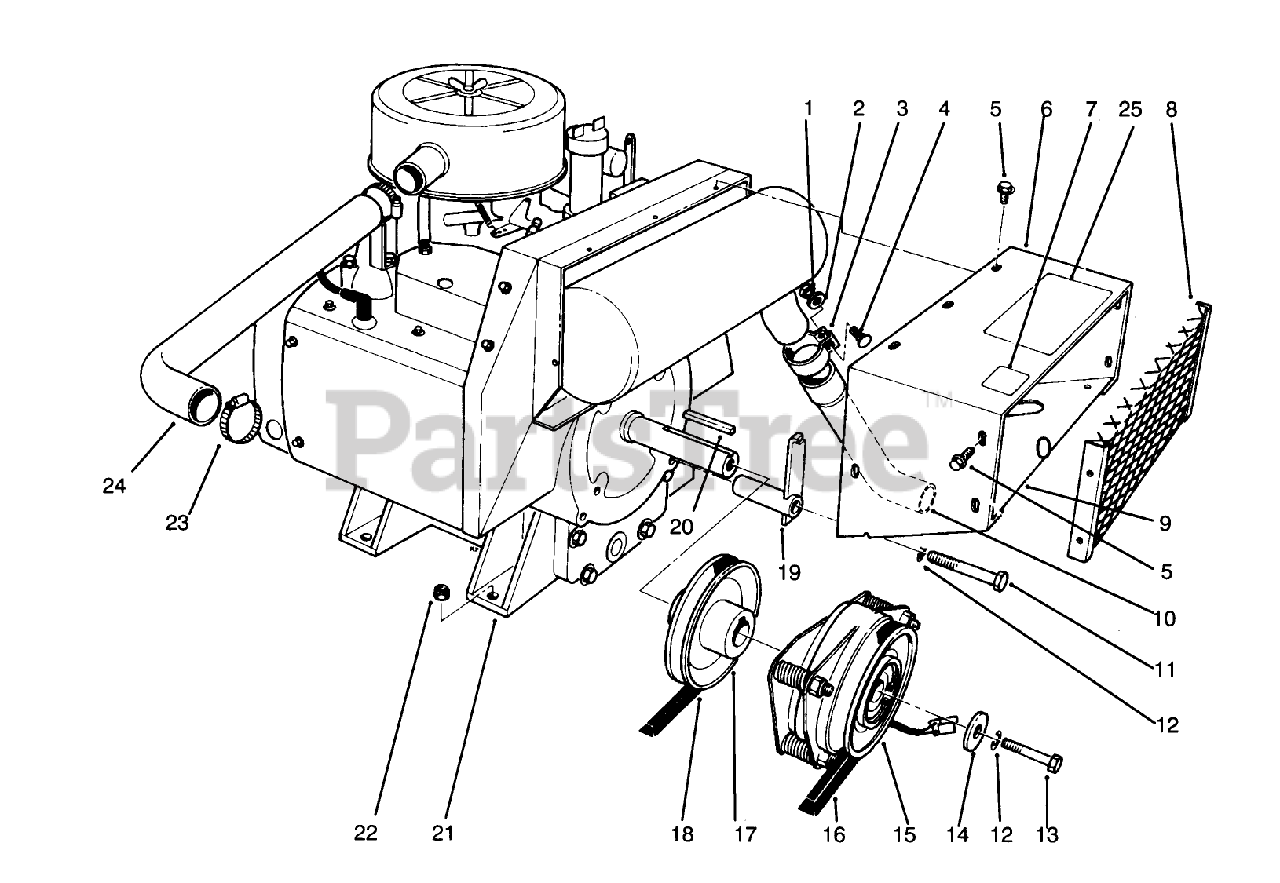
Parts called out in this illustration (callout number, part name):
1	NUT-HEX
2	WASHER-LOCK
3	Clamp Assembly (Incl. Ref. #1, 2 & 4)
4	SCREW-CARR
5	SCREW-HHFTF
6	ENGINE DUCT WA B
7	DECAL-SURFACE, HOT
8	SCREEN WA B
9	BOTTOM DUCT B
10	EXHAUST PIPE
11	SCREW-HH
12	WASHER-LOCK
13	SCREW-HH
14	WASHER-CLUTCH
15	BRAKE CLUTCH ASM
16	V-BELT, JACKSHAFT
17	ENGINE PULLEY
18	V-BELT, TRACTION
19	Anchor Bracket
21	Engine
22	NUT-LOCK, NI
23	CLAMP-HOSE
24	AIR CLEANER HOSE
25	DECAL - SERVICE INSTR.
26	SCREW-HH
27	SCREW-HWHTF
28	Mount-Engine (Ref.)
